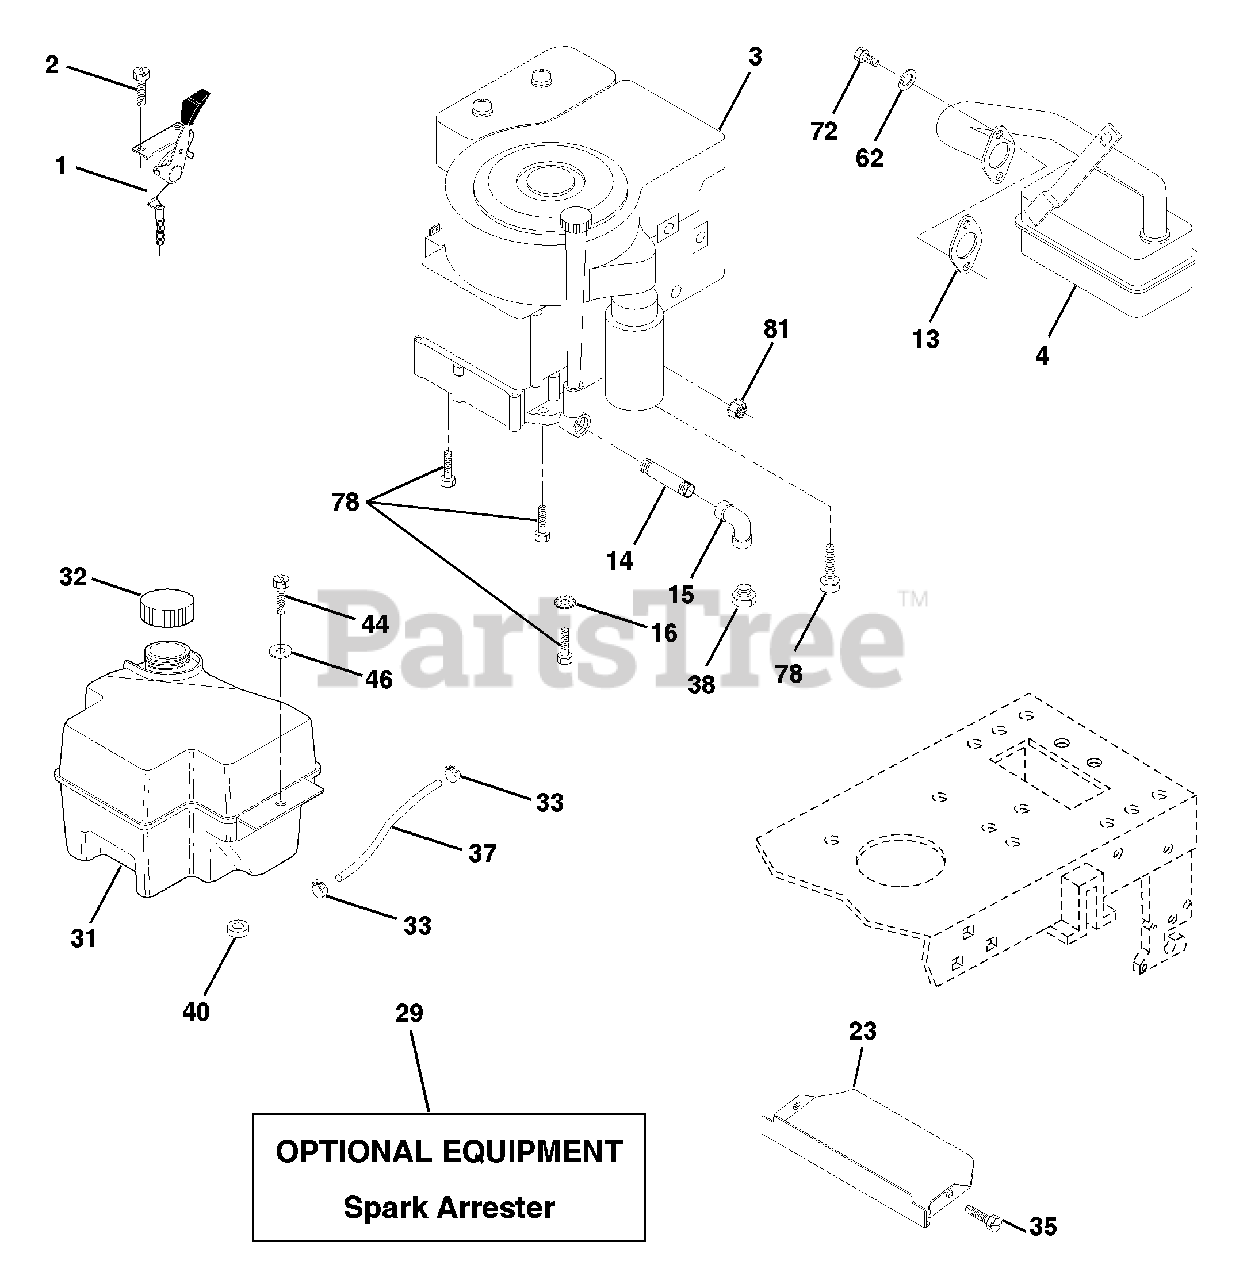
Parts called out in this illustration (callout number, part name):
1	Control Th/ch 23 5 LH Flag
2	Screw Hex Thd Cut 1/4-20x5/8 T
4	Muffler LT B&S 12/12.5/13HP
13	Gasket Eng 1 313 Id Tin Plated
14	Nipple Pipe 3/8 Npt X 3"
15	Elbow Std 90 Degree 3/8-18 Npt
16	Washer Lock Ext Tooth 3/8
23	shield Brn/Dbr Guard
29	Kit Spark Arrestor (Flat Scrn)
31	Tank Fuel Front 2 00
32	Cap Asm Fuel W/sym Vented
33	Clamp Hose Black
35	Screw
37	Line Fuel 20"
38	Plug Oil Drain
40	Bushing Snap Nyl Blk Fuel Line
44	Screw Hexwsh Thdrol 1/4-20 x 3/4
46	Washer 9/32 X 7/8 X 16 Ga
62	Washer Lock Hvy Hlcl Spr 5/16
72	Screw Hexhd Cap 5/16-18 x 3/4
78	Screw Thdrol 3/8-16 x 1-1/4 TYTT
81	Nut Flange 1/4-20 Starter Nut
